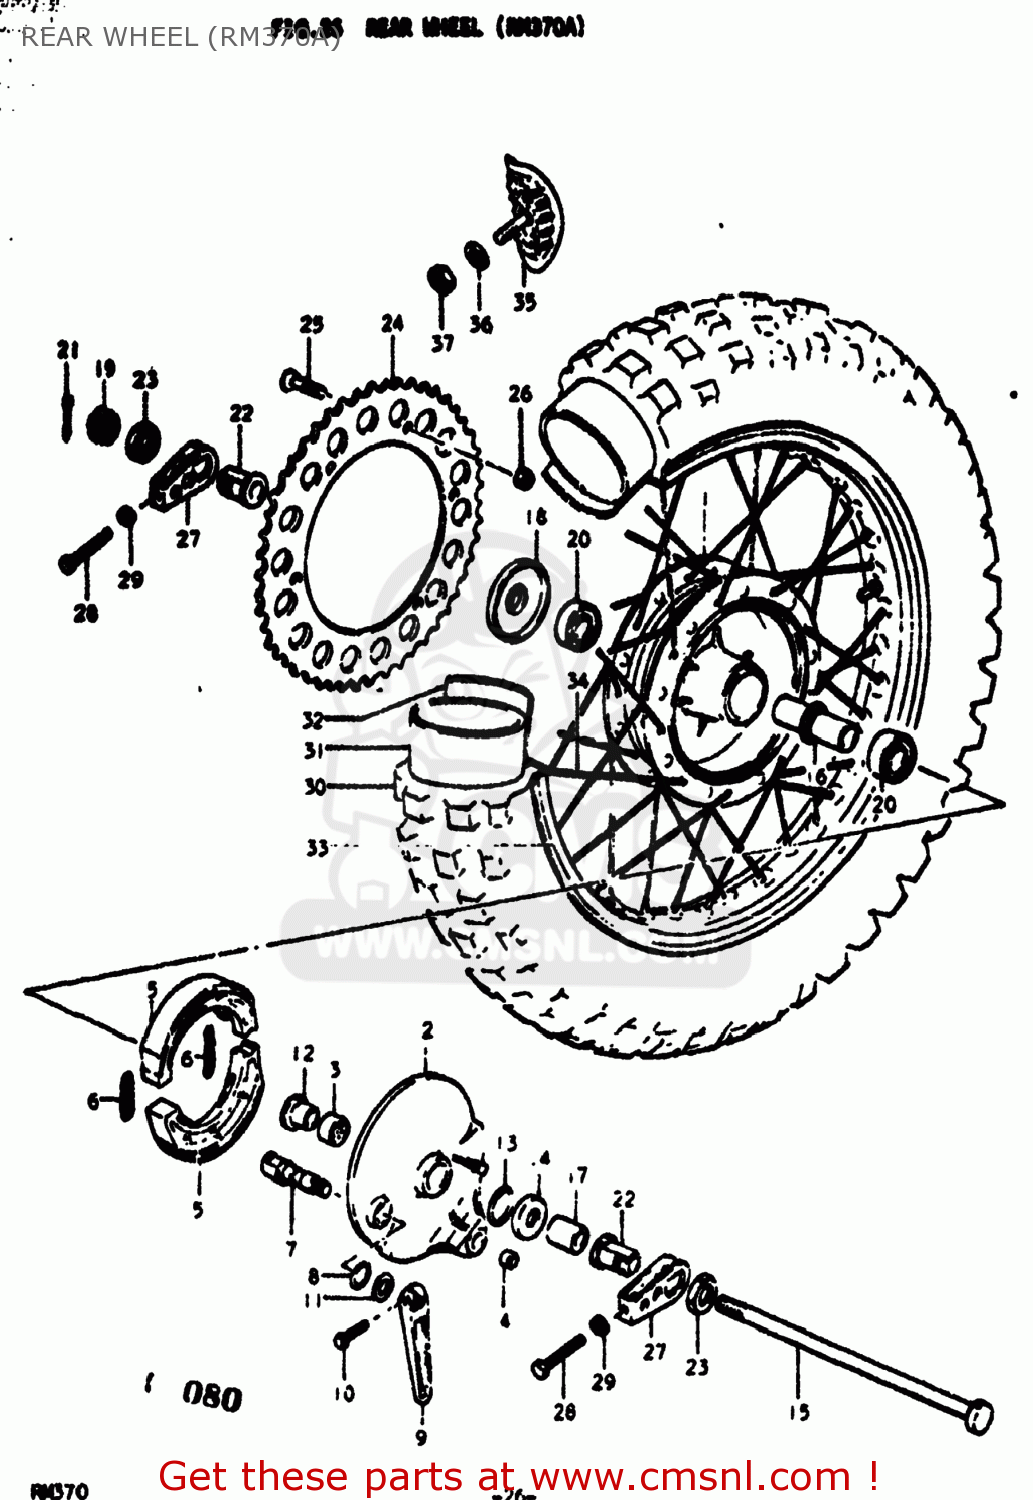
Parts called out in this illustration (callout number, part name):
1	HUB COMP,REAR
2	PANEL,REAR HUB
3	BUSHING
4	PIN,CALIPER BRACKET
5	SHOE,BRAKE
6	SPRING
7	CAM,FRONT BRAKE
8	O-RING,BOSS
9	LEVER,FRONT BRAKE CAM
10	BOLT
11	WASHER (15X24X1.6)
12	BUSHING
13	O-RING
15	AXLE,REAR
16	SPACER,REAR HUB BEARING
17	SPACER
18	SPACER,REAR AXLE
19	NUT
20	BEARING
21	PIN 30X40
22	SPACER,CHAIN ADJUSTER
23	NUT
24	SPROCKET,REAR
25	SCREW
26	NUT
27	ADJUSTER,CHAIN
28	BOLT
29	NUT
30	TIRE
31	TUBE ASSEMBLY,WHEEL,INNER
32	PROTECTOR,WHEEL,INNER
33	RIM,REAR WHEEL
34	SPOKE SET,REAR
35	STOPPER,BEAD
36	WASHER
37	NUT
